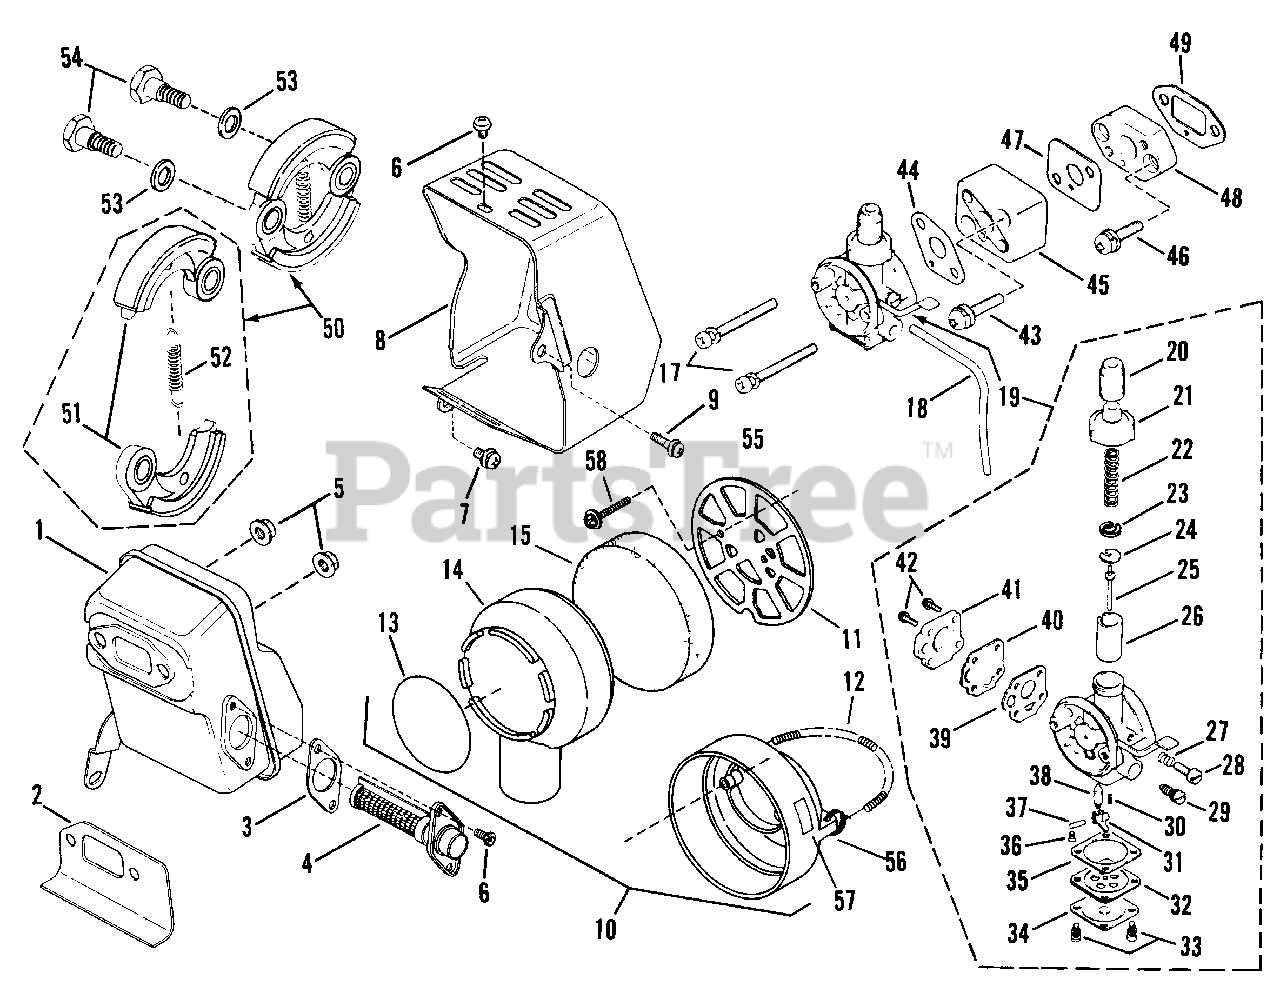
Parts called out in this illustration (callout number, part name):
1	MUFFLER
2	GASKET, Muffler
3	GASKET, Spark Arrester
4	SPARK ARRESTER
5	LOCKNUT
8	COVER, Muffler
9	SCREW
10	ASSM'Y, Air Cleaner
12	RING
14	COVER, Cleaner
15	ELEMENT
16	SCREW, Cover
17	SCREW, Carburetor
18	TUBE, Overflow
19	CARBURETOR ASSM'Y.
20	CAP, Rubber
21	CAP, Mixing Chamber
22	SPRING, Throttle
23	CLIP, Needle
24	RETAINER, Spring
25	NEEDLE, Jet Assm'y.
26	VALVE, Throttle
27	SPRING, Throttle Adj. Screw
28	SCREW, Throttle Adj.
29	NEEDLE, Main Jet Assm'y.
30	SPRING, Inlet Valve
31	ARM, Float
32	DIAPHRAGM, Main Assm'y.
34	COVER, Main Daiphragm
35	GASKET, Main Diaphragm
36	SCREW, Float Pin Set
37	PIN, Float
38	VALVE, Float
39	GASKET, Main Diaphragm
40	DIAPHRAGM, Pump
44	GASKET, Carburetor
45	FLANGE, Intake (B)
48	FLANGE, Intake (A)
49	GASKET (A)
50	CLUTCH ASSM'Y.
51	SHOE, Clutch
54	BOLT, Clutch
56	CASE, Cleaner
57	LABEL, Choke
58	SCREW & WASHER
